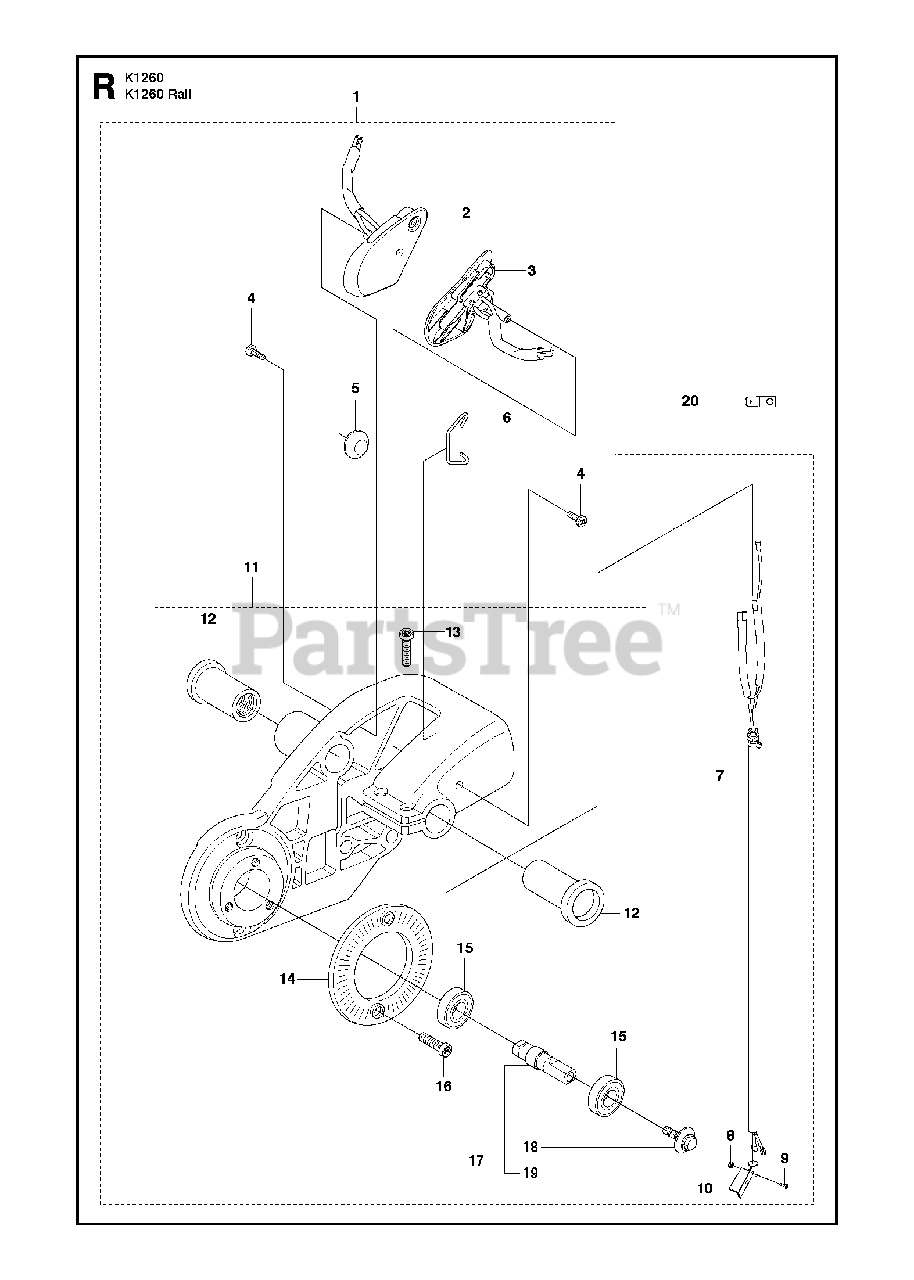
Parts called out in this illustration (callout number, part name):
1	BEARING HOUSING ASSY"14"" Rail Stop Switch, Incl. 2 - 11"
2	STOP SWITCHRH
3	STOP SWITCHLH
4	SCREW CRPANT
5	SPACING BLOCK
8	HEXAGON LOCKING NUT
9	SCREW CRPANM
11	BEARING HOUSING ASSY"14"" Rail, Incl. 12 - 17"
11	BEARING HOUSING ASSY"16"" Rail, Incl. 12 - 17"
11	BEARING HOUSING ASSY"16"" Rail USA, Incl. 12 - 17"
13	SCREW IHSCFM
15	BALL BEARING
16	SCREW ITXSCM
17	SHAFTIncl. 18 - 19
